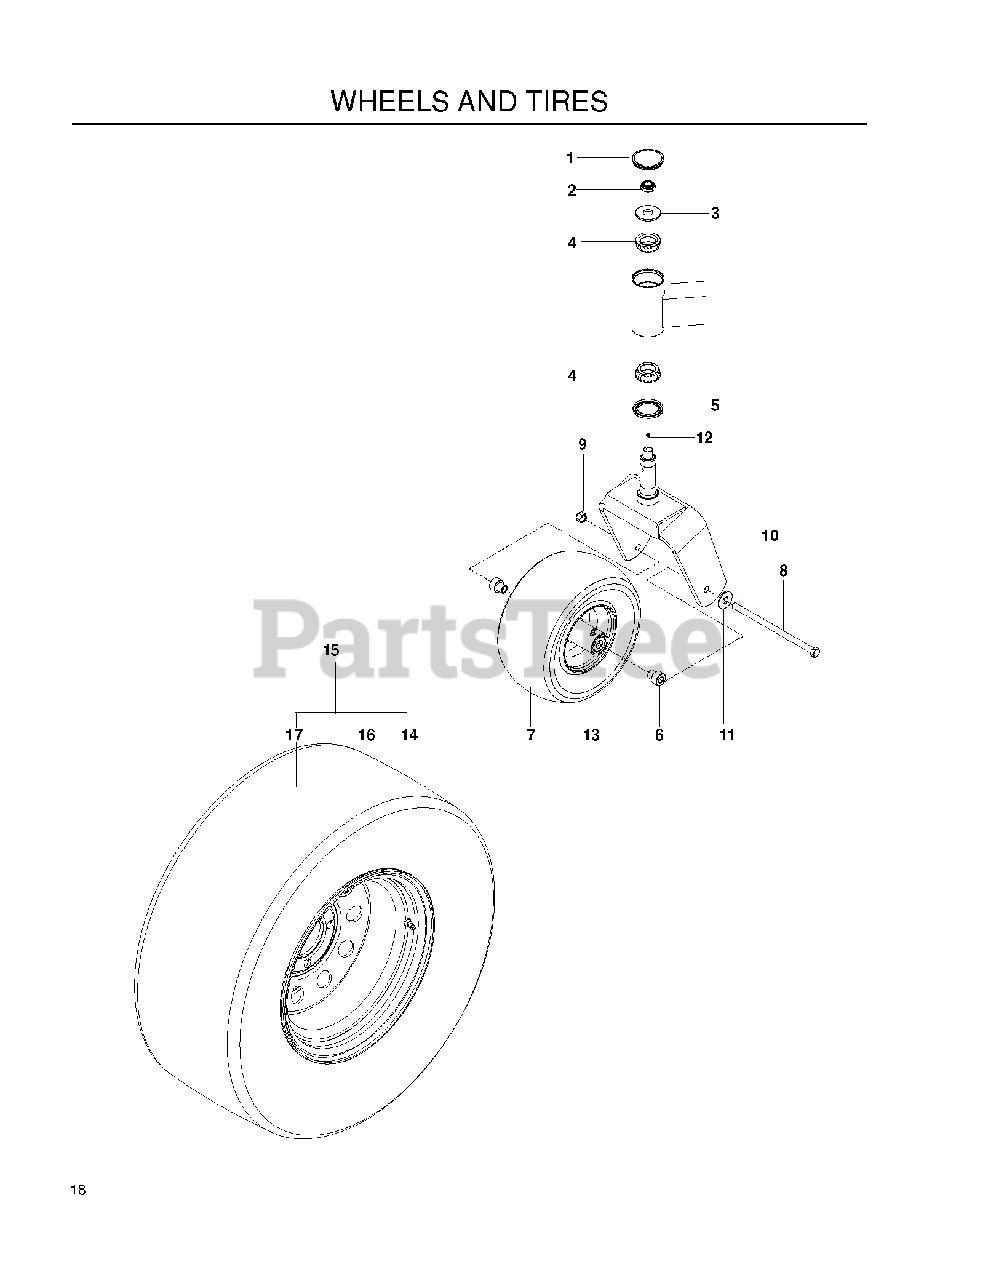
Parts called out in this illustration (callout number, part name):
1	CAP, DUST
2	NUT, 3/4-16 HEX THIN NYLOC ZD
3	WASHER, 3/4 HARDENED
4	BEARING W/CUP TAPPER ROLLER
5	SEAL, BEARING
6	AXLE SPACER
7	FRONT TIRE ASSY
8	HEX SCREW 1/2-13 X 9.5 GR5
9	NUT, 1/2-13 HEX FLG NYLOC ZD
10	FORK.CASTER.BLUE
11	WASHER 1/2" FLAT
13	ZERK
14	VALVE STEM TR-412
15	TIRE ASSY 24-12
17	TIRE.TURF.MASTER.24X12-12
